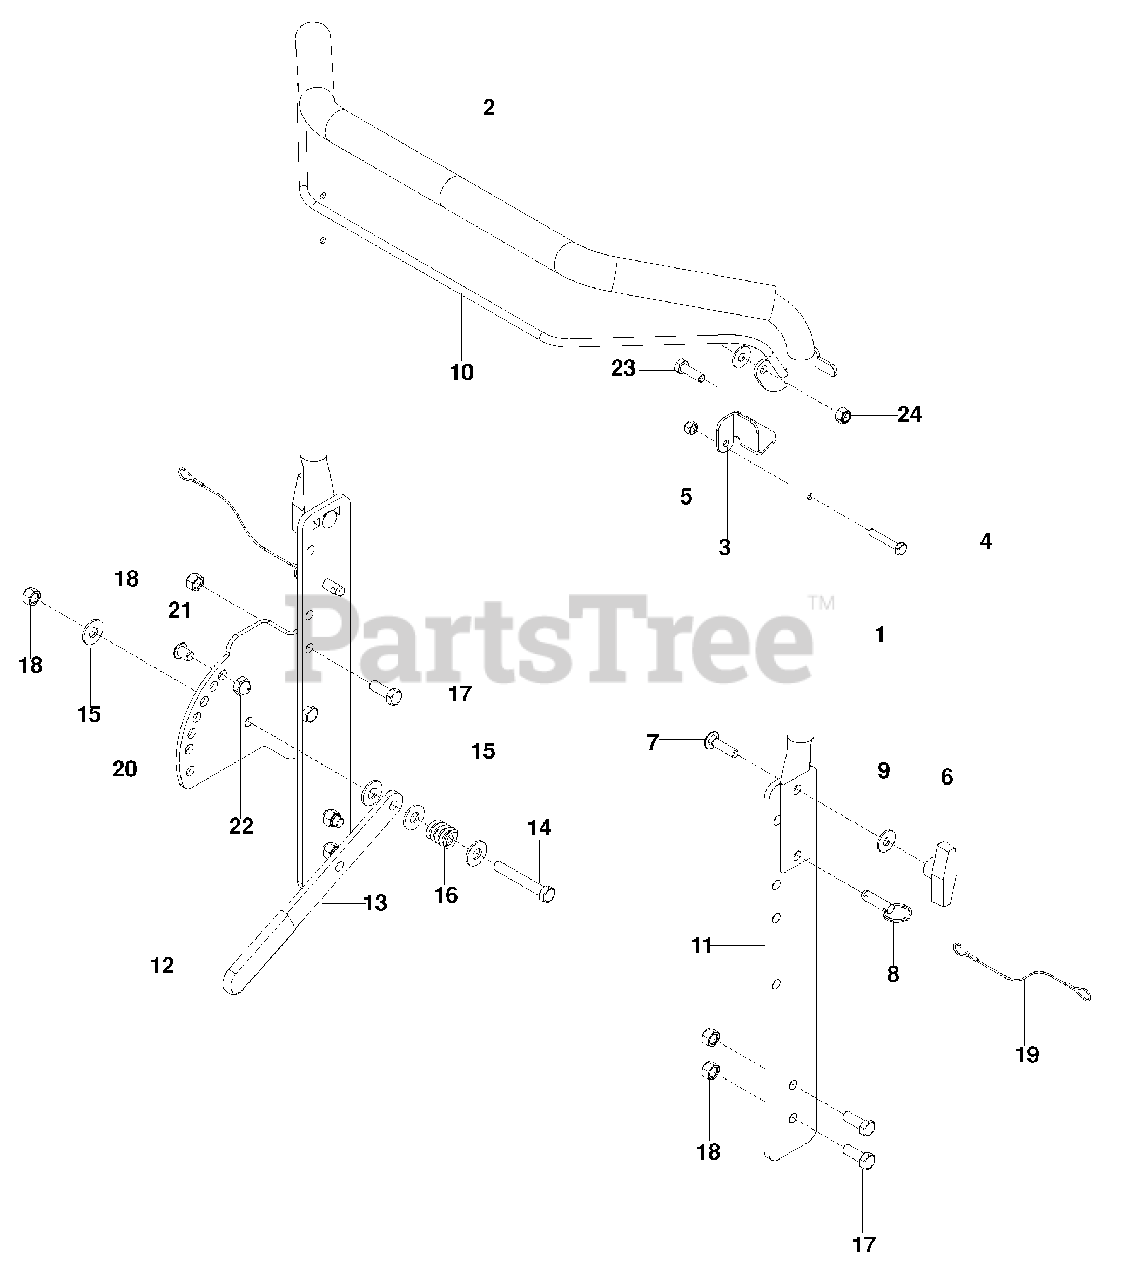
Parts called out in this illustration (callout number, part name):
4	HCS 1/4-20 x 1 1/2
5	NUT 1/4-20 NYLOC
7	RHSNB 5/16-18 x 1 1/4
9	WASHER 5/16
11	HANDLE SIDE
12	GRIP, LEVER
14	HCS 3/8-16 x 2
15	WASHER 3/8
17	HCS 3/8-16 x 1
18	NUT 3/8-16 NYLOC
20	HEIGHT PLATE
21	HCS 3/8-16 x 1/2 BUTTONHD
22	NUT 3/8-16 ACRON
23	HCS 5/16-18 x 1
24	NUT 5/16-18 NYLOC
